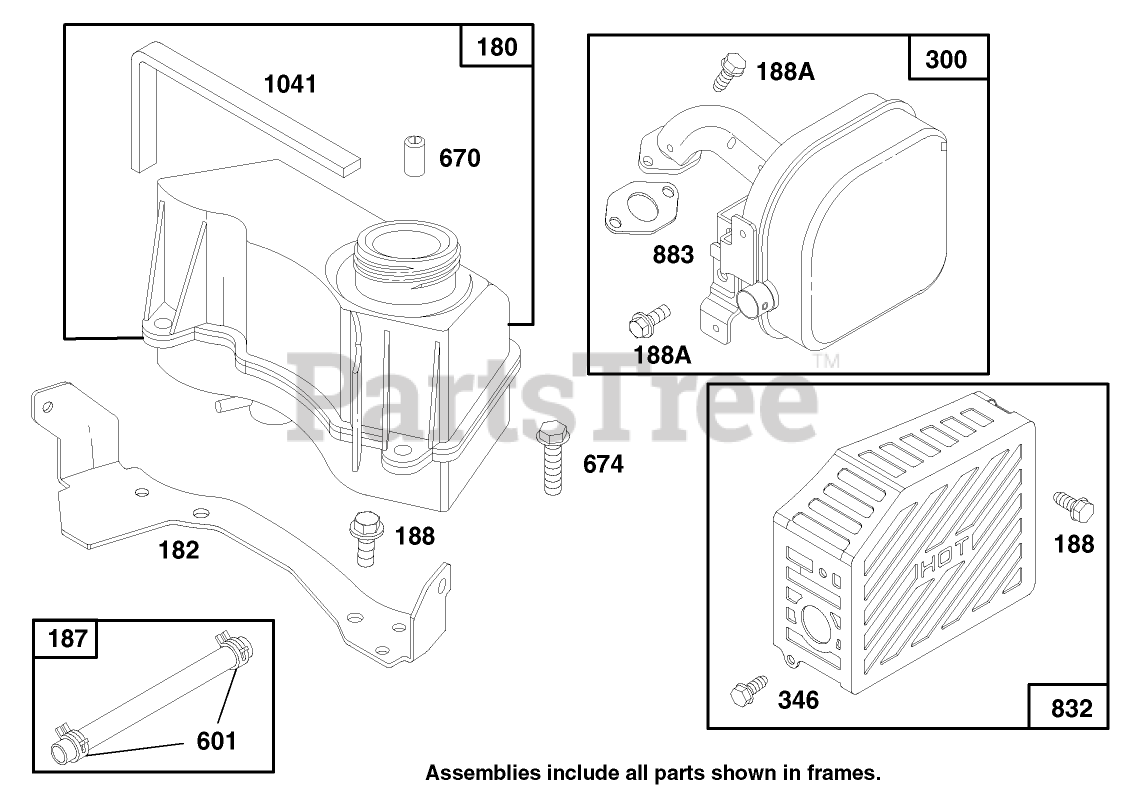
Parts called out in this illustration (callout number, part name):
180	TANK ASSY - FUEL
187	BRIGGS 296004
188	SCREW - HEX HEAD
300	MUFFLER - EXHAUST
670	SPACER
674	SCREW - HEX HEAD
